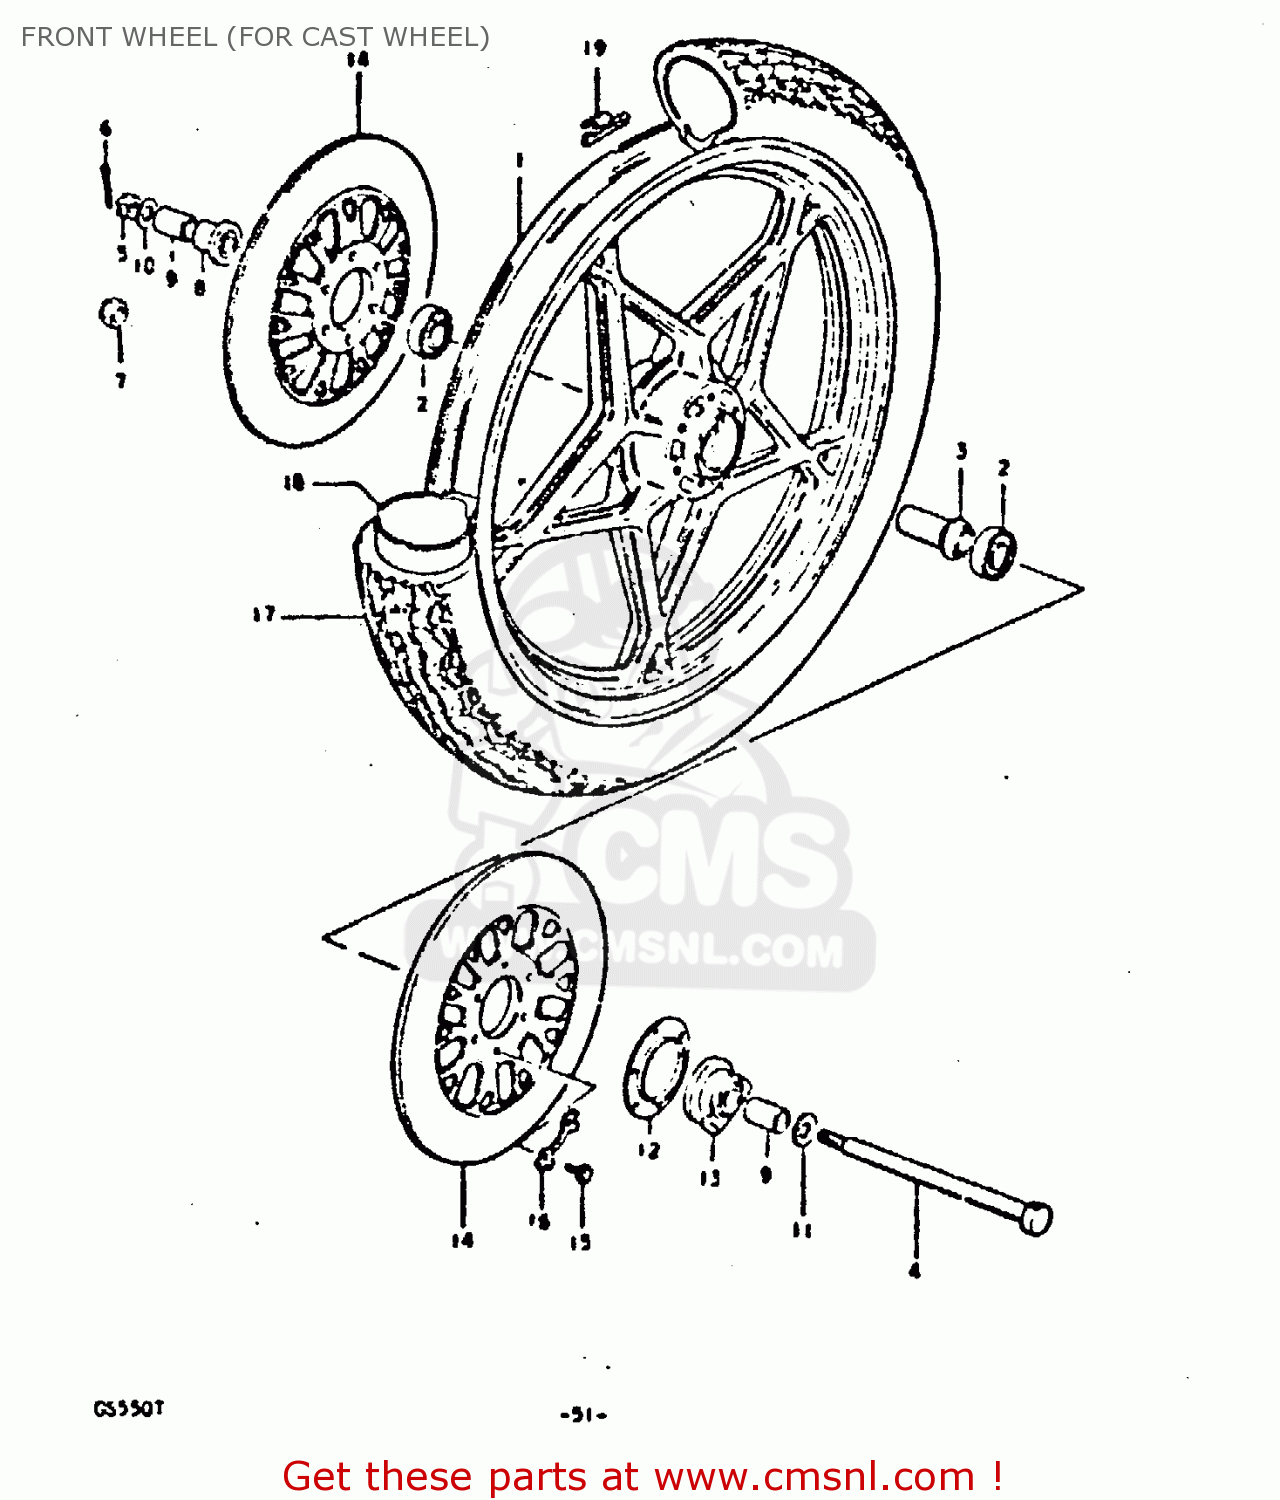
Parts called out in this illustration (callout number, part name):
1	WHEEL, FRONT
2	BEARING
3	SPACER,FR HUB BEARING
4	AXLE,FRONT
5	NUT 12MM
6	COTTER PIN
8	SPACER,FR AXLE,R
9	SPACER(15X22X30)
10	WASHER
12	DUST SEAL,SPEEDOMETER GEAR BOX
13	BOX ASSEMBLY,SPEEDOMETER GEAR
14	DISC,FR BRAKE
15	BOLT(8X25)
16	WASHER
17	TIRE,FRONT
18	TUBE,INNER
19	BALANCER,WHEEL
